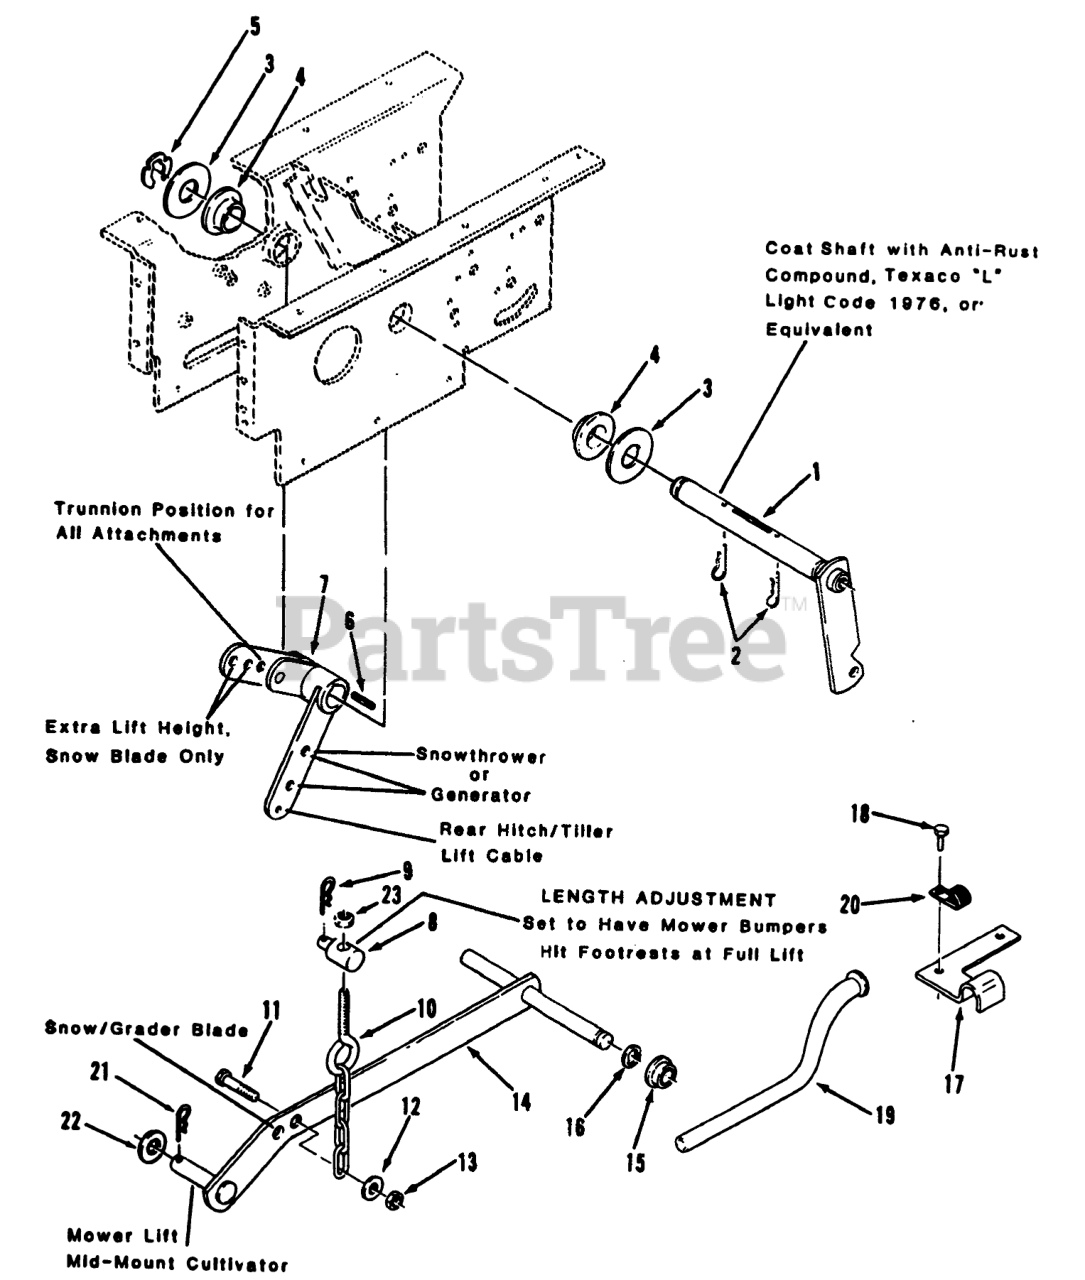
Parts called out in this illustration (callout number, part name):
1	WLDMT-LIFT ARM
2	Pin-Cotter
3	WASHER-FLAT
4	BEARING-FLANGE
5	PIN-SPRING
6	KEY-SQUARE
7	WLDMT-LIFT LEVER
8	TRUNNION
9	Hairpin Cotter
10	CHAIN-LIFT
11	SCREW-HH
12	WASHER-PLAIN
13	NUT-LOCK, NI
14	Bar-Lift
15	BUSHING
16	RING-RETAINING, EXTERNAL
17	Tube-Clamp
18	SCREW-HH, LOCK
19	TUBE-CONDUIT R
20	CLIP
21	Hairpin Cotter
22	WASHER-FLAT
23	NUT-LOCK, NI
